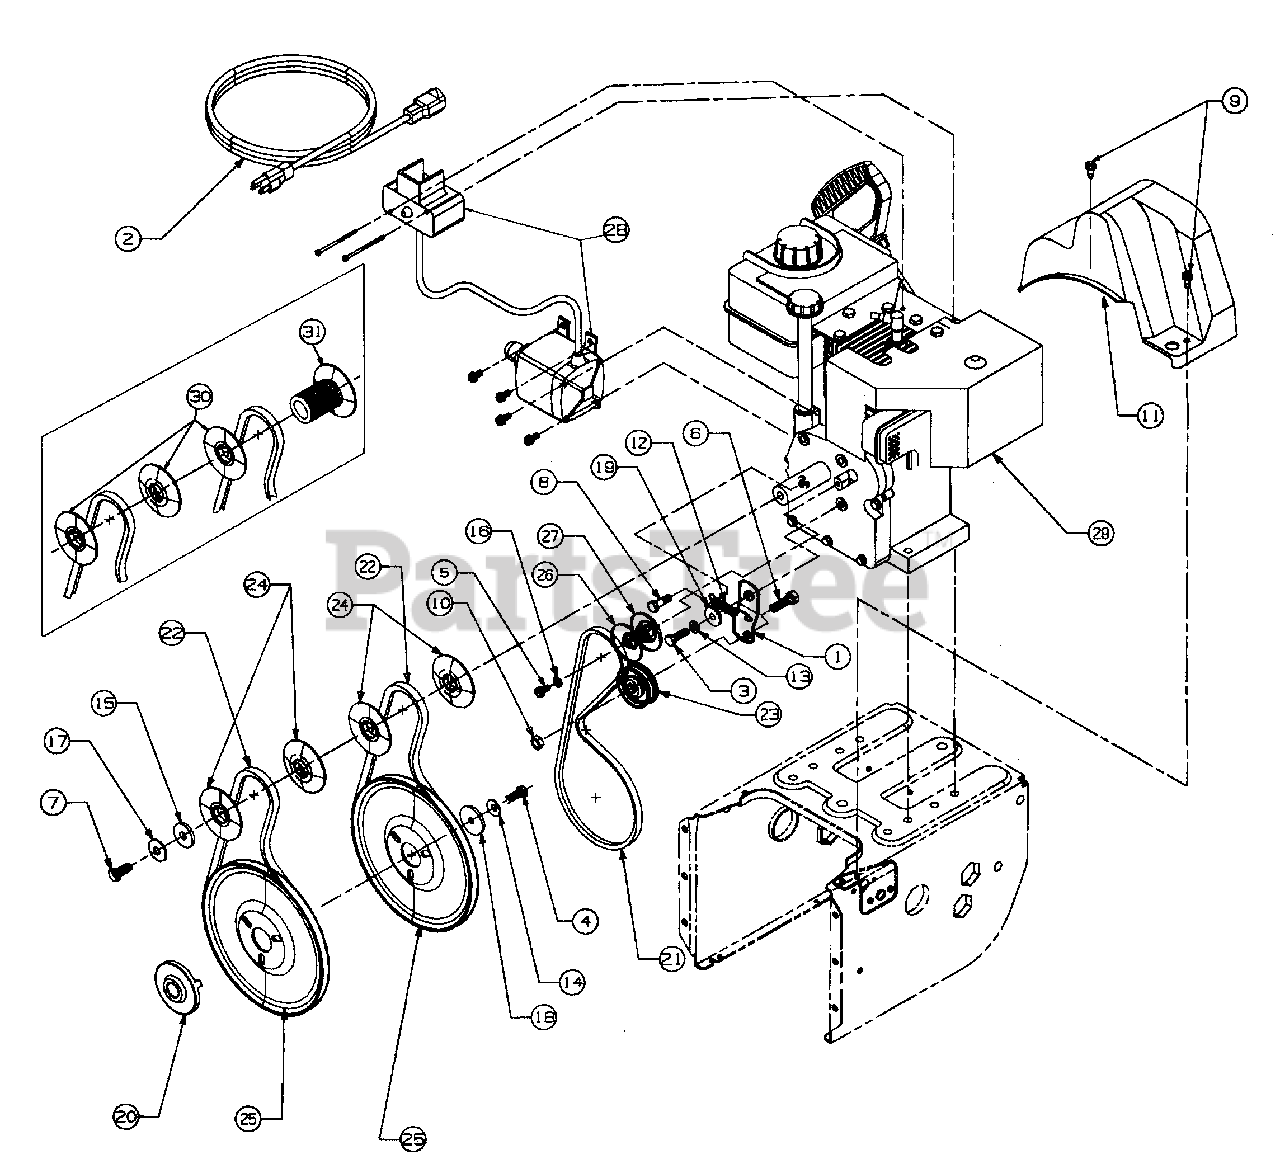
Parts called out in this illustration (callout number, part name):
3	Screw, Hex Cap 5/16-24 x 1.0 GR5
4	Screw, Hex Cap 5/16-24 x .75 GR5
5	Screw, Hex Cap, 1/4-28 x .5
6	Screw, Hex Cap, 3/8-16 x 1.25
7	Screw, Hex Cap 3/8-24 x 1.5 GR5 (724TE only)
8	Screw, Hex Cap 5/16-24 x 1.0 GR5
9	Screw, Hex Wash Hd Tapp 1/4-14 x .625
10	Nut, Hex Jam Lok, 3/8-16
11	Belt Cover
12	Spring, Extension
13	Washer, Lock 5/16
14	Washer, Bell, .345 x .88 x .06
15	Washer, Flat, .406 x 1.25 Hdn
16	Washer, Lock, 1/4
17	Washer, Bell, .39 x 1.13 x .062
18	Washer, Flat, .34 x 1.5 x .15 Hdn
19	Shoulder Spacer
20	Pulley Adapter
21	V-Belt, 3/8 x 30.0
22	V-Belt, 3V x 34.9
23	Pulley, Flat Idler
24	Pulley Half (926TE only)
25	Pulley, Auger
26	Pulley Half
27	Pulley Half
28	Starter Kit (724TE)
29	Engine
30	Pulley Half (724TE only)
31	PUlley Half (724TE only)
